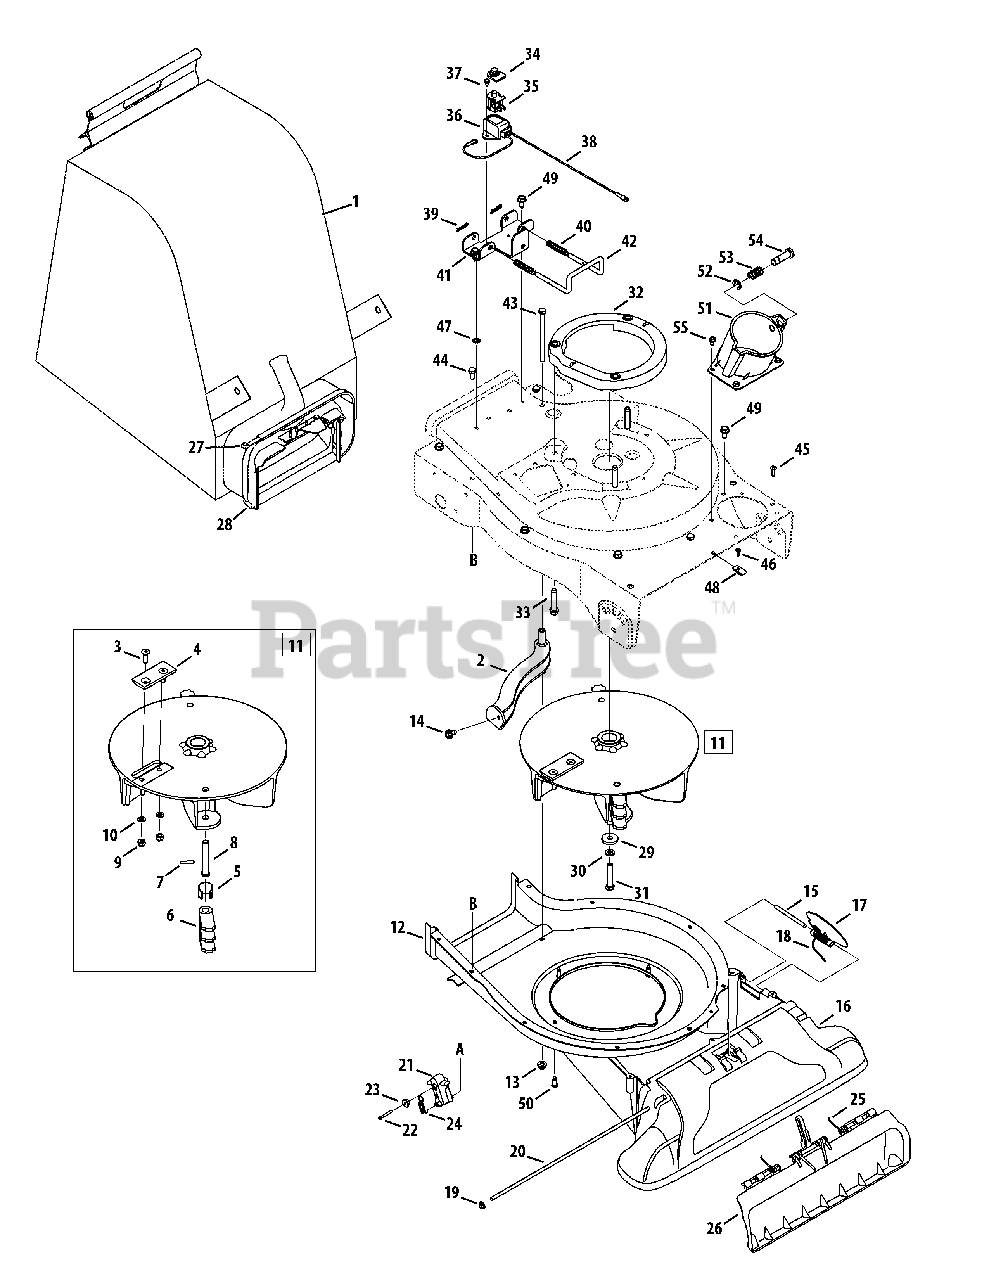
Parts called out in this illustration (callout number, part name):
1	Bag Assembly (incl. Ref 27)
2	Screen Assembly
3	Hex Screw, 5/16-24 x 1.0
4	Chipper Blade
7	Spiral Pin
8	Clevis Pin
9	Lock Nut, 5/16-24
10	Lock Washer, 5/16
11	Impeller Assembly(Incl. Ref.# 3 - 10)
12	Lower Flail Housing
13	Flange Lock Nut, 5/16-18
14	Screw, 5/16-18 x.500
17	Base Adapter Door
18	Torsion Spring
19	Cap Speed Nut, 1/4
20	Pivot Rod
21	Nozzle Door Lever
22	Hex Screw, #8-18 x 1.25
23	Shoulder Spacer
24	Extension Spring
25	Nozzle Door Torsion Spring
26	Nozzle Door
27	Tie Strap, 42"
28	Chute Assembly
29	Flat Washer, .375 ID x 1.25 OD
30	Lock Washer, 3/8
31	Hex Cap Screw, 3/8-24 x 2.75
32	Engine Spacer Assembly
33	Screw, 3/8-16 x 1.875
34	Switch Cover
35	Safety Switch
36	Safety Switch Cover
37	Hex Washer Screw, #10-16 x.50
38	Wire Harness
39	Cotter Pin
40	Compression Spring
41	Mounting Bracket
43	Hex Cap Screw, 5/16-18 x 4.5
44	Hex Cap Screw, 5/16-18 x.625
45	Screw, #12-16 x.750
46	Screw, #10 - 16 x.500
47	External L-Washer, 5/16
48	Speed Nut
49	Hex Index Screw, 5/16-12 x.750
50	Shldr. Screw, #12-24 x .30 x .46
51	Hose Base Adapter Assembly (Incl. Ref.# 52-54)
52	E Ring, .500 Dia
53	Compression Spring
54	Clevis Pin
55	Screw, 1/4-20 x .500
